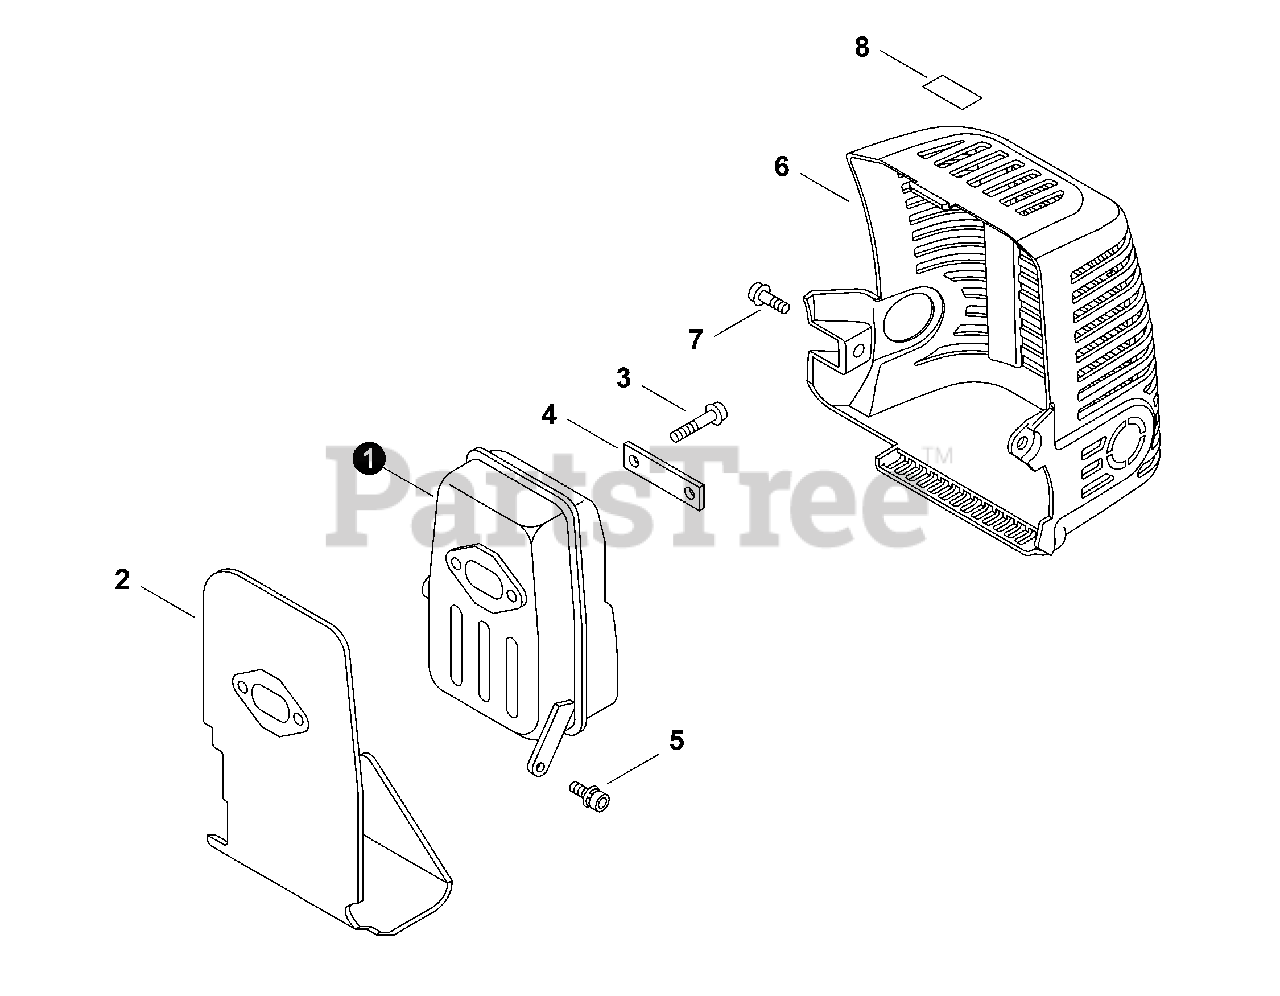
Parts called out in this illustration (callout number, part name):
1	MUFFLER
2	GASKET, EXHAUST
3	BOLT 6×60
4	PLATE, EYE
5	BOLT 5×12
6	COVER, MUFFLER
7	BOLT 5×12
8	LABEL, CAUTION - HOT
